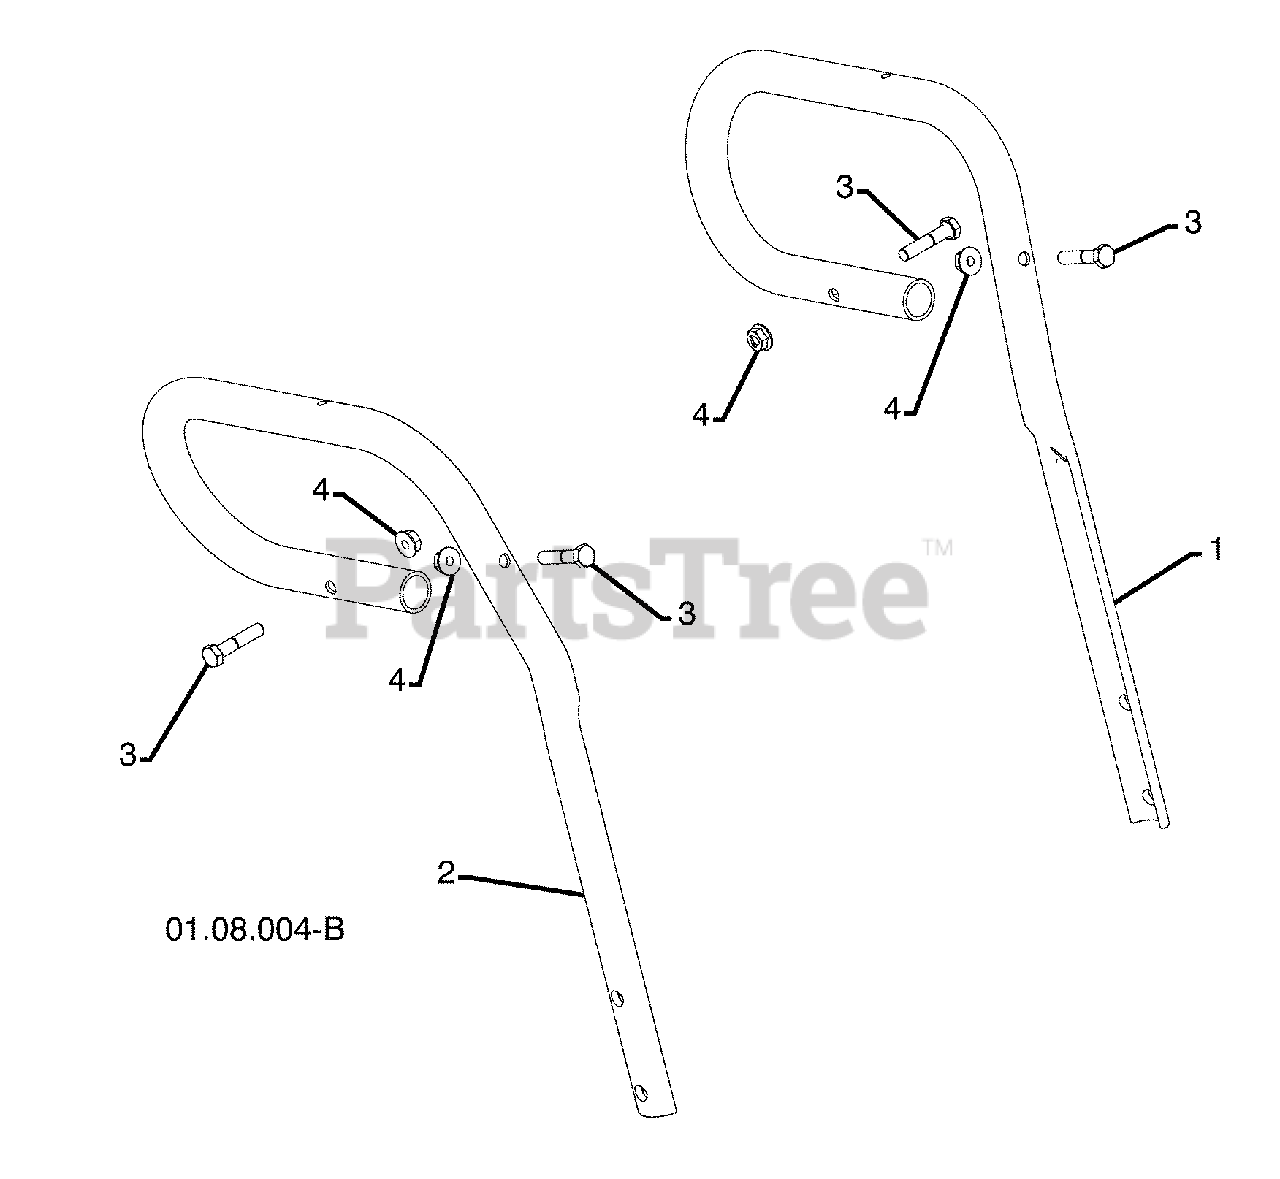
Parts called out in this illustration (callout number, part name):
1	LOOP HANDLE LH
2	LOOP HANDLE RH
3	SCREW 5/16-18 X 1.50
4	NUT 5/16-18
